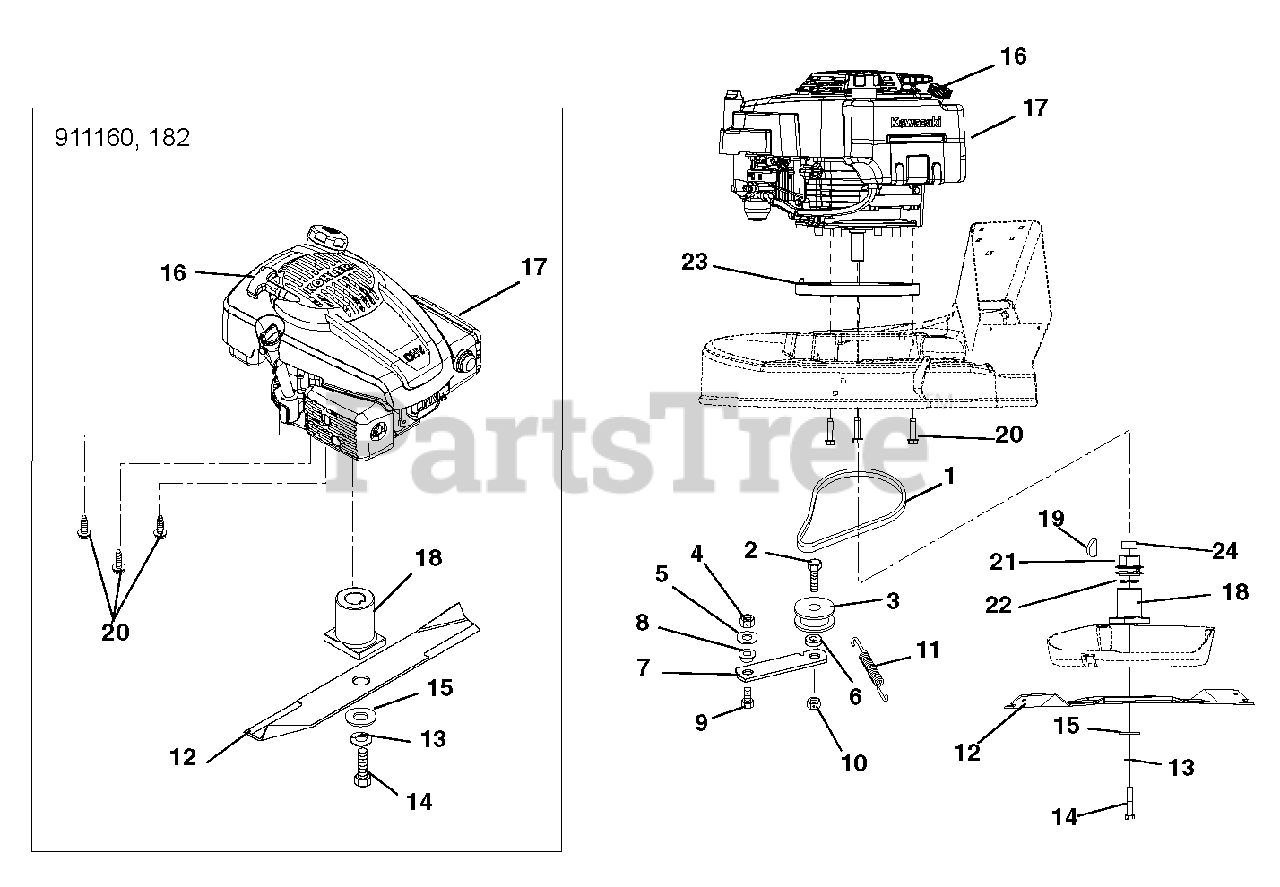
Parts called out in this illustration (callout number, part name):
1	V-Belt 3L Section (911183, 184)
2	Bolt, Hex .44-14 x 1.50 Grade 5 (911183, 184)
3	Idler, Flat 1.75 x .47 (911183, 184)
4	Nut, Locking Center .31 -18 (911183, 184)
5	Washer, Flat Steel .344 x .688 x .065 (911183, 184)
6	Bushing, Sleeve .469 x .75 x .43 (911183, 184)
7	Idler Arm (911183, 184)
8	Bushing, Flange .325 x .501 x .250 x 1.120 (911183, 184)
9	Bolt, Hex .31-18 x .75 Grade 5 (911183, 184)
10	Nut, Locking Center .44-14 (911183, 184)
11	Spring, Tension .043 x .44 x 3.31 (911183, 184)
12	Blade, 21" Mower
13	Washer, Locking .38 x .094
14	Bolt, Hex .38-24 x 2.00 Grade 8 (911160, 182)
15	Washer, Flat Steel .390 x 1.50 x .125
16	Recoil Start Handle
17	Engine, Kohler XT-7 (911160)
18	Adapter, Blade (911160, 182)
19	Key, Woodruff .156 x .625 x .25 SAE #6 (911183, 184)
20	Screw, Tapping .38-16 x 1.00 Hex Washer Head (911160, 182)
21	Pulley, Crank (911183, 184)
22	Washer, Wave .885 x 1.311 x .125 (911183, 184)
23	Plate, Engine Shim (911183, 184)
24	Spacer, .875 x 1.125 x .525 (911183, 184)
